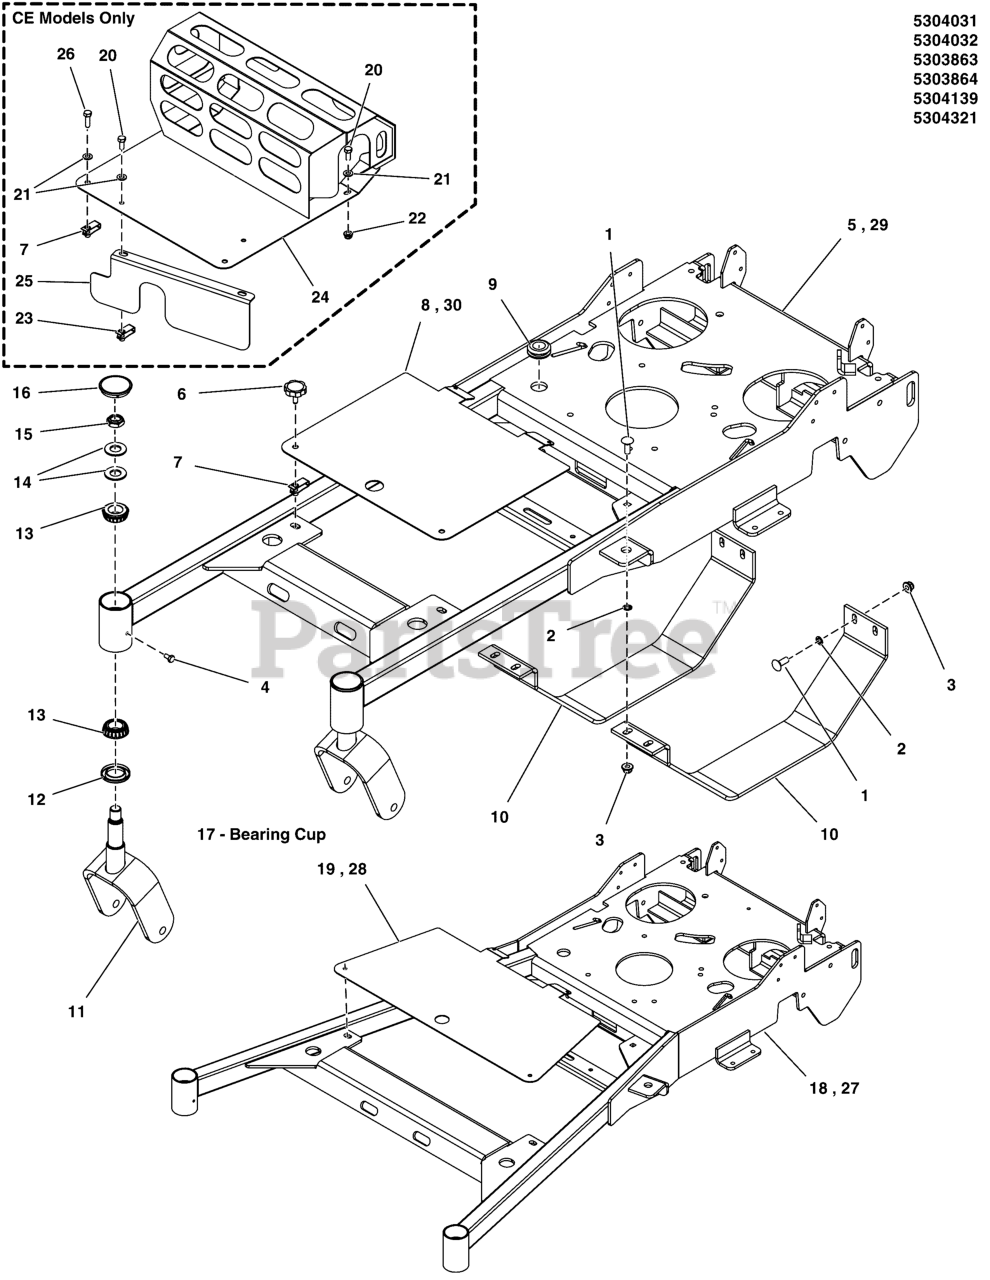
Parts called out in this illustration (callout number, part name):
1	BOLT,3/8-16X1.000,RND HD CRRG,ZINC/CLEAR
2	3/8 PUSHNUT BOLT RETAINER
3	NUT, 3/8 - 16 HEX NYLOCK FLANGE
4	BOLT, 1/4-28 X 1/2, GD5 YZ
5	WELD, MAIN FRAME, FW25 - 36 - RED
6	KNOB, 5/16-18 X 1.00, ROSETTE, BLK
7	BODY CLIP, 5/16-18 -1/4 MATERIAL
8	GUARD, WALK, FRONT FRAME, 36 - RED
9	GROMMET, 7/8"ID, 1/4" THICK STK
10	PLATE, TRANS GUARD SW25 - BLK
11	WELD, CASTER YOKE, SNP DD - RED
12	SEAL, GREASE
13	BEARING, TAPERED ROLLER, 1"
14	WASHER, BELLEVILLE - 1.500 X .755
15	NUT, 3/4-16, HEX JAM NYLON LOCK
16	CAP, GREASE, LOW PROFILE
17	BEARING, TAPERED ROLLER, 1"
18	WELD, MAIN FRAME, FW25 - 48 - RED
19	PLATE, FRONT FRAME GUARD FW25 48 - RED
20	BOLT, 5/16-18 X 3/4 GD5
21	WASHER, 5/16" SAE
22	NUT, 5/16-18 HEX NYLOCK FLANGE NUT
23	BODY CLIP, 5/16-18-7GA MATERIAL
24	WELD, MUFFLER GUARD, FW2536CE - RED
24	WELD, MUFFLER GUARD, FW25 36CE - RED
25	PLATE, FRONT DECK GUARD,FW2536RDCE-RED
25	PLATE, DECK GUARD, FRONT, FW25 36CE - RED
26	BOLT, 5/16-18 X 1" GRD5 YZ
27	WELD, MAIN FRAME, W25, 48/52 - RED
28	PLATE, GUARD, FRONT FRAME, W25 48/52 - RED
29	WELD, MAIN FRAME, W25, 36 - RED
30	PLATE, FRAME GUARD, W25 36 - RED
